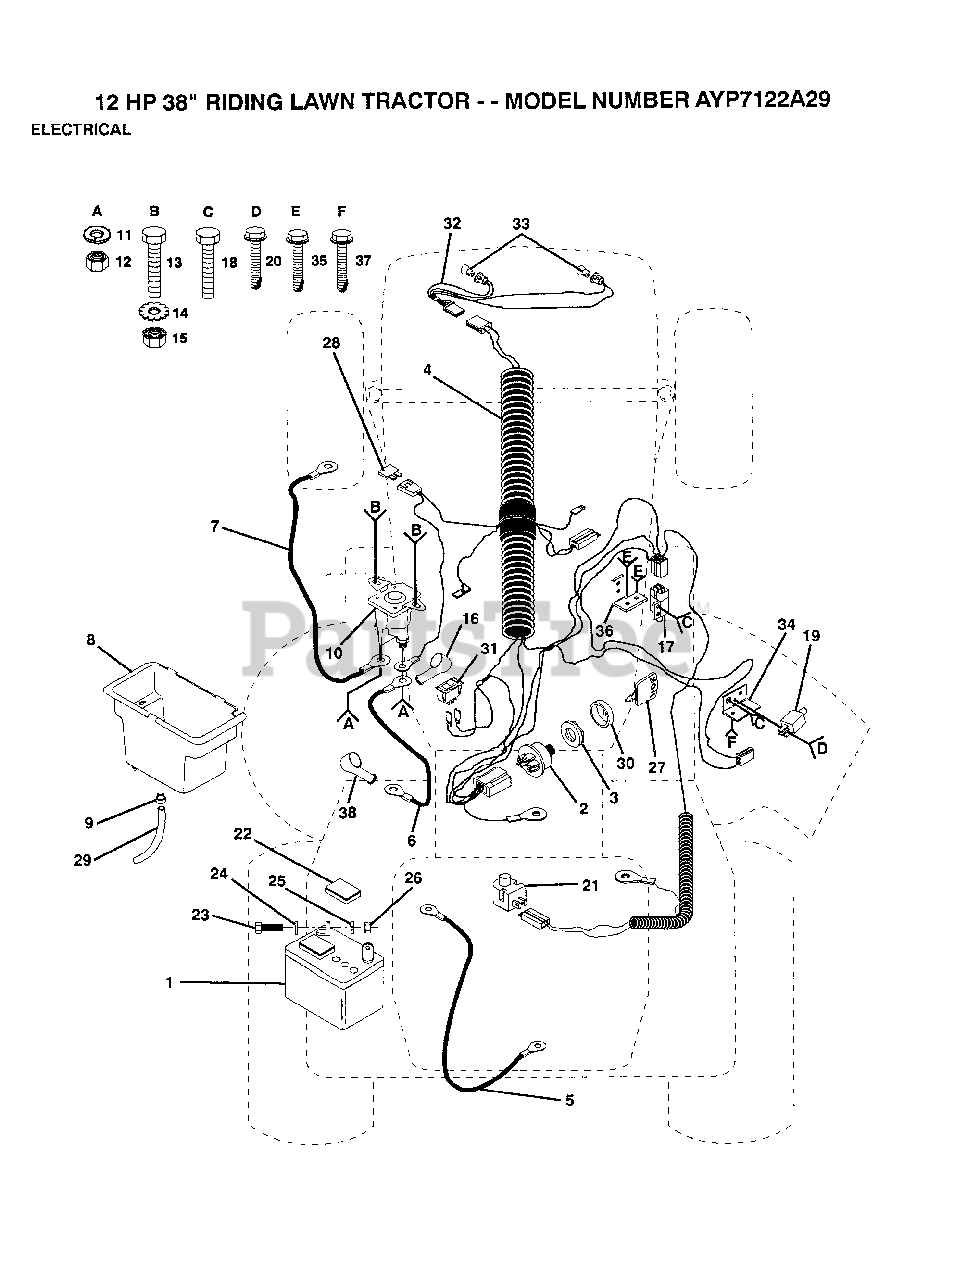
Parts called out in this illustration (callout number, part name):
3	NUT IGNITION
4	IGN HARNESS
5	CABLE T
7	"CABLE T, BATTERY"
8	BTRY CASE W/O LID
9	HOSE CLAMP T
12	NUT
13	BOLT
15	NUT
17	SWITCH INTERLOCKT
18	SCREW
19	SWITCH-INTER. GT
20	SCREW
21	SWITCH SEAT
22	"CAP,BATTERY "
23	BOLT LT
24	WASHER
25	LOCKWASHER
28	FUSE HYT
31	SWITCH LT
34	BRACKET LT
35	SCREW
36	SWITCH BRACKET
37	SCREW
